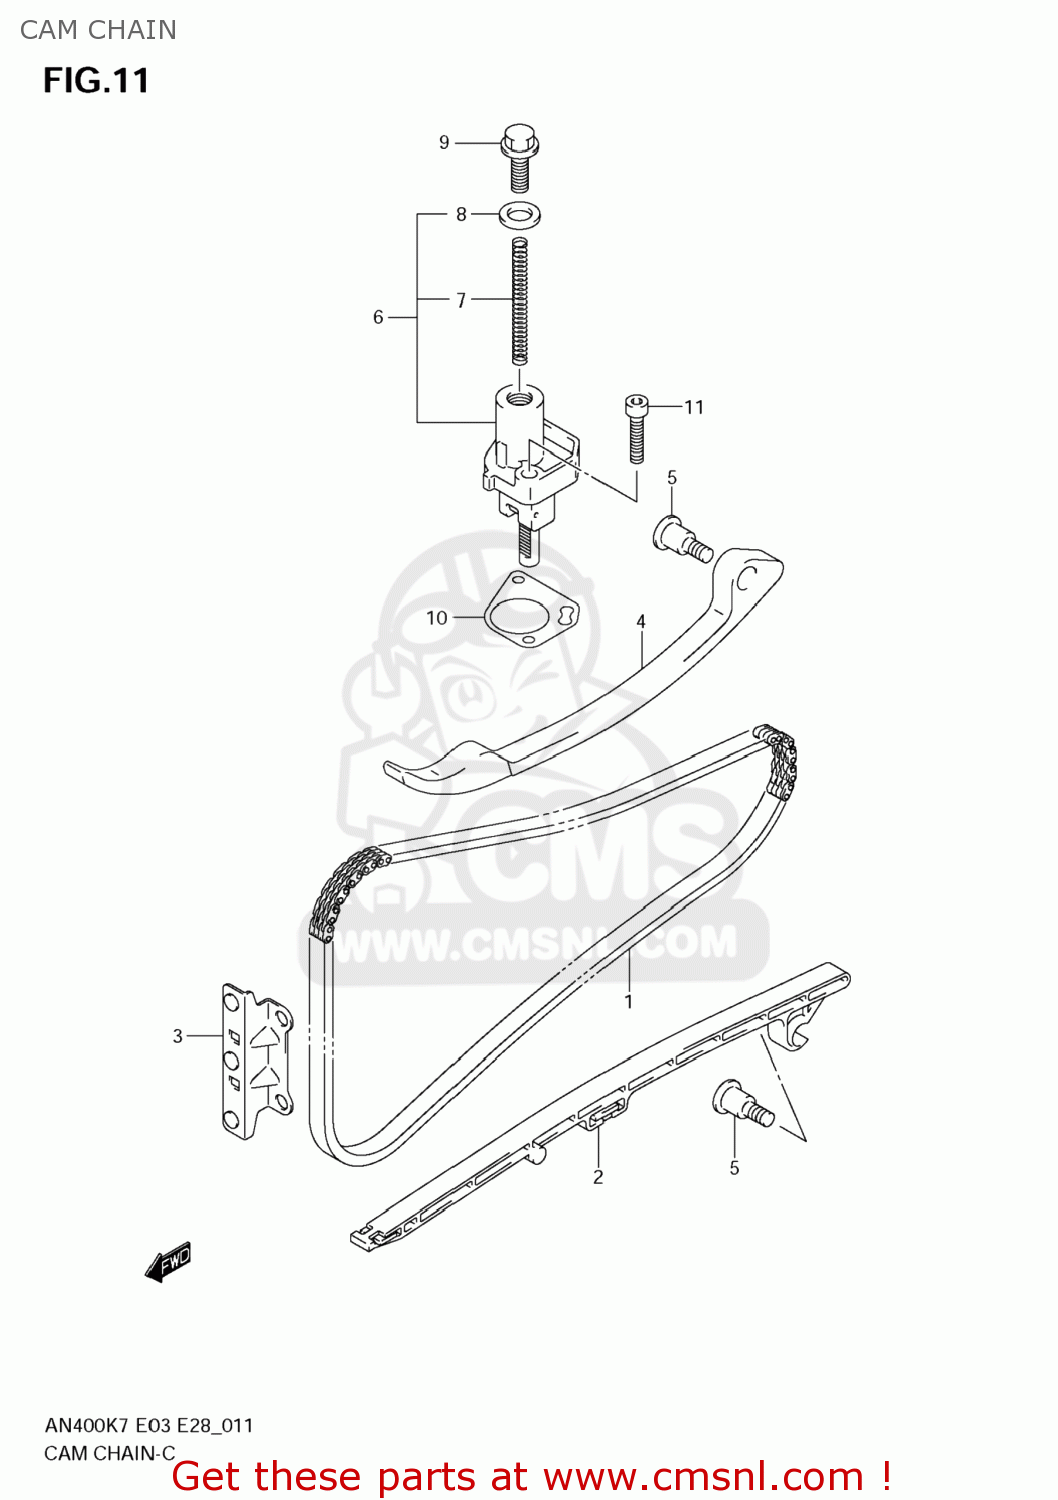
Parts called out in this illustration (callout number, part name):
1	CHAIN,CAMSHAFT DRIVE
2	GUIDE,CAM CHAIN NO.1
3	GUIDE,CAM CHAIN NO.2
4	TENSIONER,CAM CHAIN
5	BOLT,CAM CHAIN TENSIONER
6	ADJUSTER ASSY,TENSIONER RR
7	SPRING
8	GASKET,TENSIONER ADJUSTER (NAS)
9	PLUG,TENSIONER ADJUSTER
10	GASKET,TENSIONER ADJUSTER (NAS)
11	BOLT
